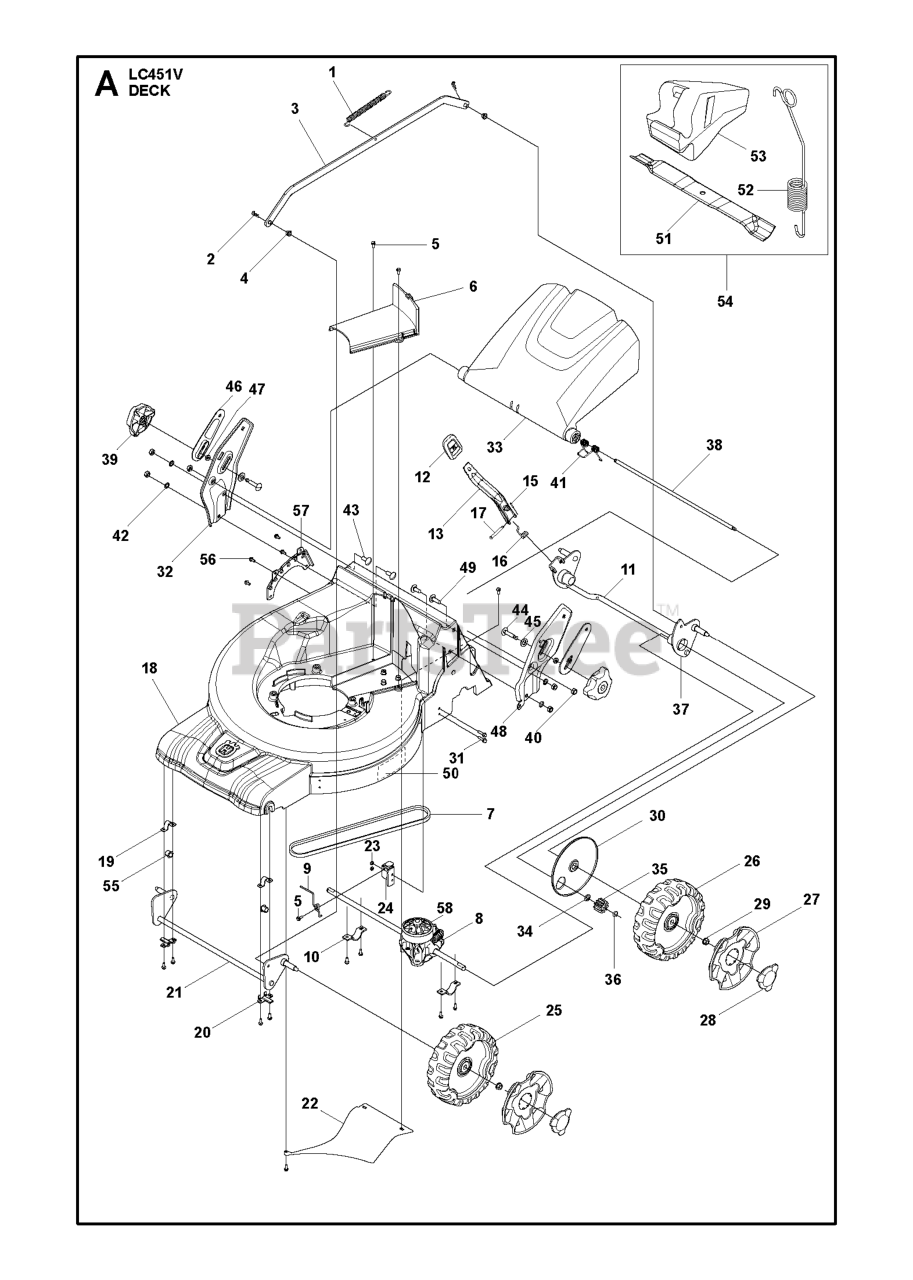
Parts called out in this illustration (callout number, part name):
7	Belts
25	WHEEL ASSY 210, IDLE, MEDIUM
31	SCREW M6S 5X20
37	Ball Bearings
40	LOCKNUT M8
41	SPRING 51 CAST
42	WASHER BRB 8.4X17
47	NUT ML6M M8
58	TRANSMISSIONS
